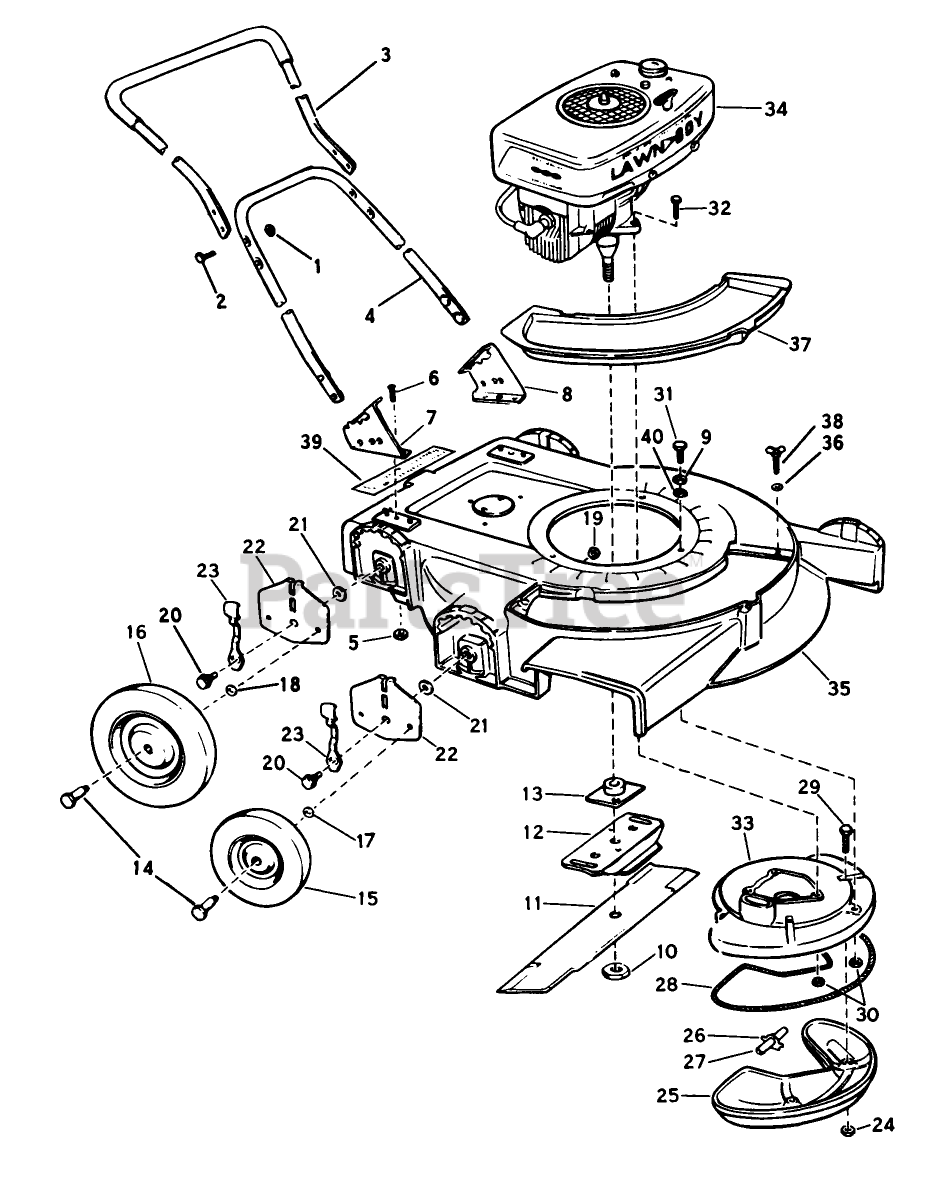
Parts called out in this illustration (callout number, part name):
1	STOP NUT
3	Handle Grip Assy. Top
6	SCREW S
10	NUT-BLADE
13	PLATE AND COLLAR ASM
14	BOLT WHEEL
17	WASHER WROUGHT
18	WASHER WROUGHT
24	LOCKNUT E
26	Gasket-Internal Tube
27	Tube-Internal Muffler
35	Housing Cover Assy. 19"
39	Decal, Instruction
